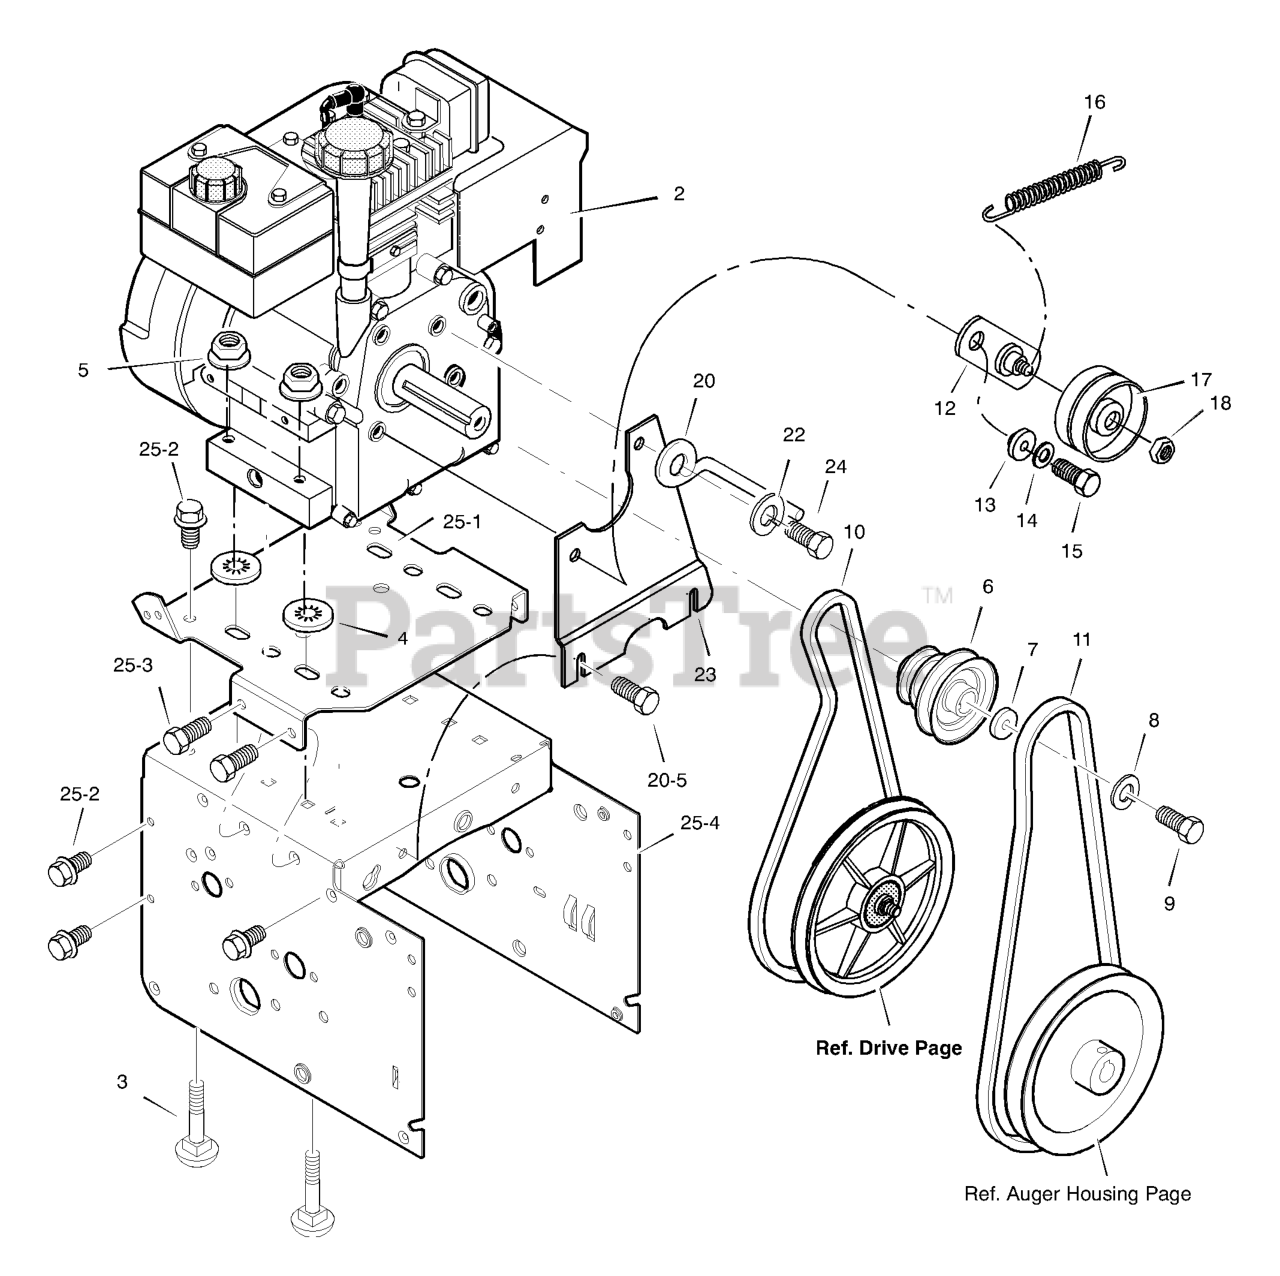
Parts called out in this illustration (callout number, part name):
2	ENGINE
3	BOLT, CARRIAGE 5/16-18
4	RETAINER, PUSH
5	NUT, HEX 5/16-18
6	PULLEY, ENGINE
7	WASHER
8	WASHER .38ID
9	SCREW, 3/8-24 x 1.00
10	BELT, V 3L 33.13LG
11	BELT, V 4L 38.1MF16" 5-10
12	BRACKET ASSEMBLY, IDLER
13	BUSHING, IDLER BRACKET
14	WASHER, SPLIT
15	SCREW 5/16-24 X 1.00
16	SPRING, IDLER TRACTION DRIVE
17	PULLEY, IDLER
18	NUT, JAM 3/8-16
20	GUIDE, BELT
22	WASHER, SPTLK .31X.58X.08
23	PLATE, ANTI VIBRATION
24	SCREW, 5/16-24 x 1.00
25	FRAME ASSEMBLY
25-1	PLATE, ENGINE MOUNT
25-2	SCREW, TAP 1/4-20 X .63
25-3	SCREW, TAP 5/16-18 X .50
25-4	FRAME, MOTOR BOX
